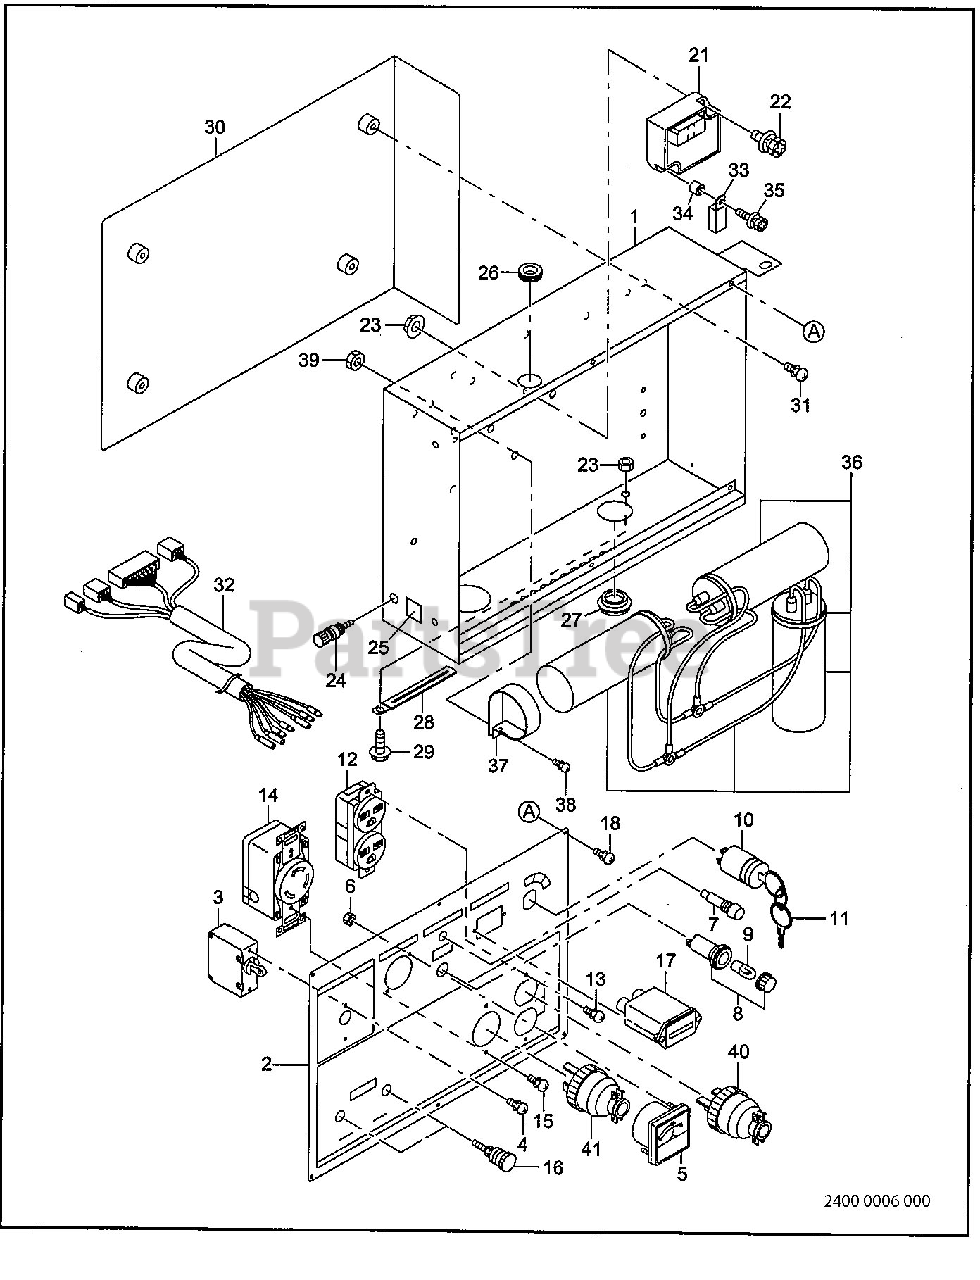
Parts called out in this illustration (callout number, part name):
1	CONTROL BOX ASSY
1	CONTROL BOX UNIT
2	CONTROL PANEL ASSY
2	CONTROL PANEL
3	BREAKER (1P-35A)
3	BREAKER (1P-30A)
3	BREAKER (1P-40A)
4	SCREW and WASHER ASSY
8	LAMP (OIL)
9	LAMP (18V-0.11A)
10	KEY SWITCH
13	SCREW and WASHER ASSY
14	AC RECEPTACLE (250V-30A, TWIST LOCK)
15	SCREW and WASHER ASSY
16	TERMINAL
18	SCREW and WASHER ASSY
21	ECU(O/S & R/C) ASSY
22	SCREW and WASHER ASSY
23	FLANGE NUT
29	FLANGE BOLT iM6x12mm)
31	SCREW and WASHER ASSY
32	WIRE ASSY
36	CONDENSER ASSY (37(JFX3)
37	CONDENSER BRACKET
38	SCREW and WASHER ASSY
40	AC PLUG (250V-15A)
41	AC PLUG (250V-30A)
